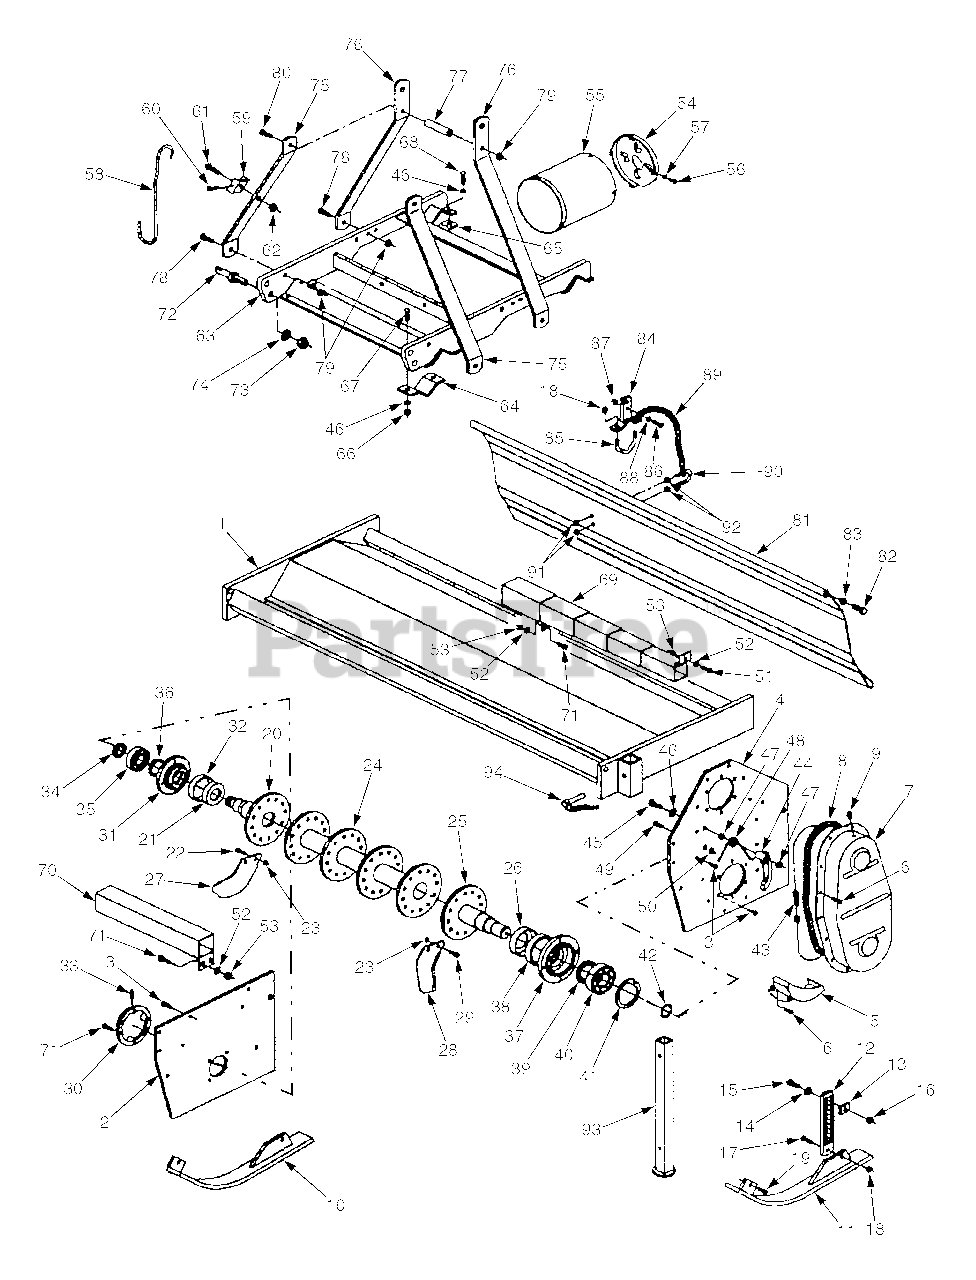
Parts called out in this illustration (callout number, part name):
2	Right Side Panel
4	Drive Panel
5	Chain Case Protection
6	Bolt, 10 x 30
7	Chain Case Cover
9	Breather Cap
10	Skid - Right
11	Skid - Left
12	Adjustment Arm
14	Threaded Washer
16	Nut M12
20	Flanged Pivot - RH
21	Dirt Shield
22	Bolt, 12 x 45
25	Flanged Pivot - LH
26	Dirt Shield
27	C-Blade - Right
28	C-Blade - Left
31	Right Support
32	Dirt Shield
33	Grease Fitting
34	Safety Nut M35x1.5
37	Left Support
43	Chain ASA 100 x 36
44	Chain Tensioner
45	Bolt, 14 x 75
46	Lock Washer, M14
49	Bolt, 14 x 60
52	Flat Washer M10
54	Protection Support
55	PTO Shaft Protection
57	Flat Washer M6
58	Driveline Hook
59	Hook Support
61	Bolt 8 x 20
63	Side Shift Complete
67	Bolt, 14 x 40
68	Bolt 14 x 35
70	Right Protection
71	Bolt, 10 x 35
74	Lock Washer M20
75	Top Hitch Support
76	Top Hitch Arm
78	Bolt 14 x 45
80	Bolt 14 x 110
82	Bolt, 18 x 80
84	Chain Hitch
86	Bolt, 10 x 30
88	Flat Washer M10
